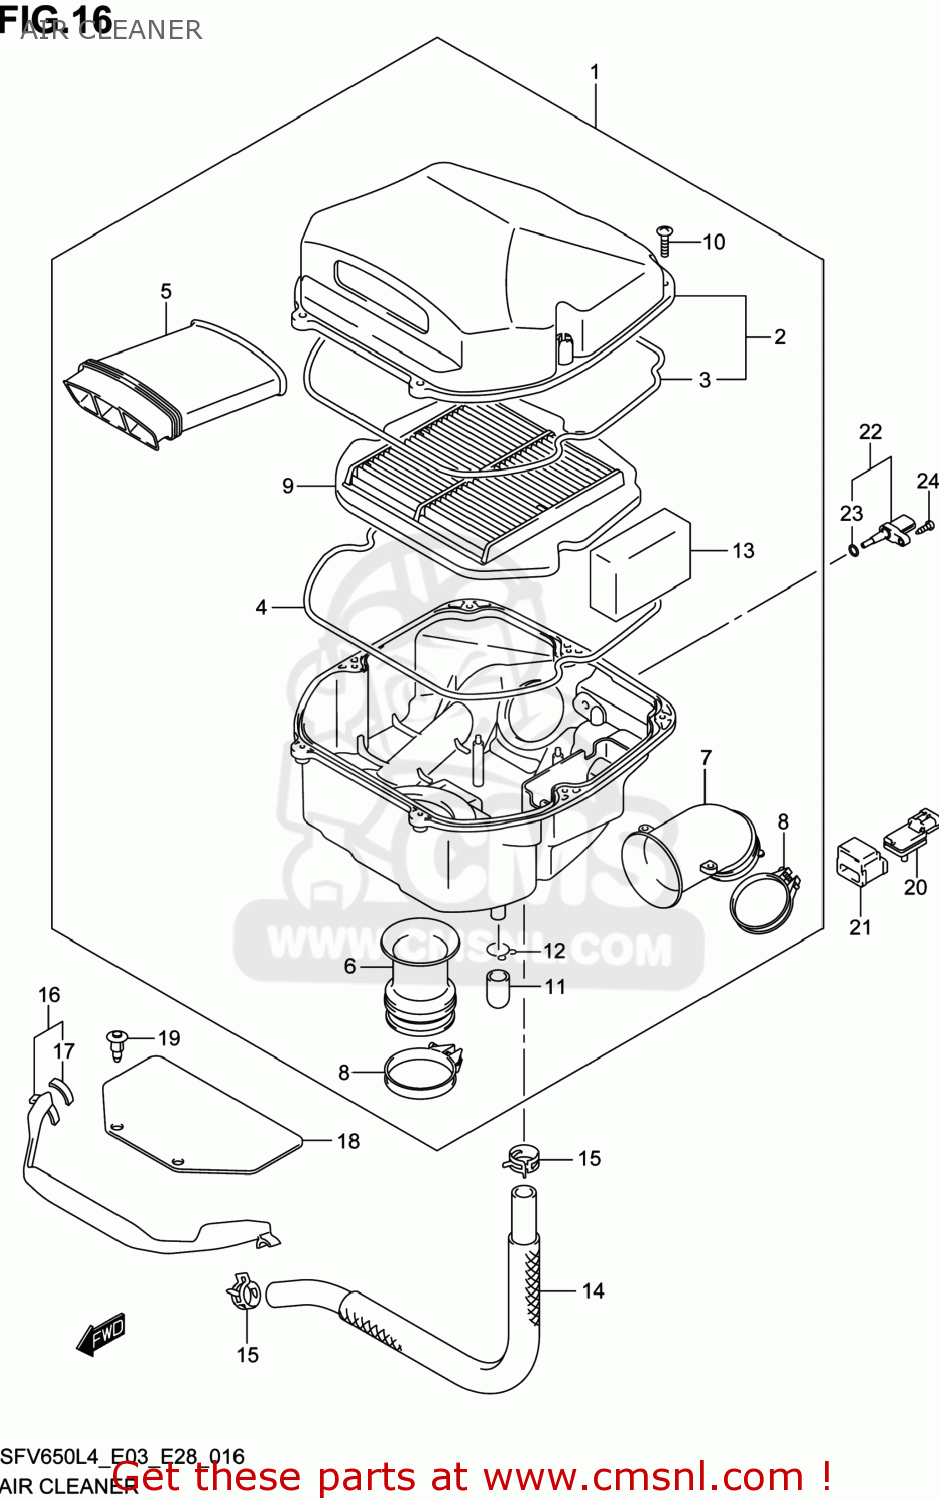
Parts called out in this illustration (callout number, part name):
1	CLEANER ASSY,AIR
2	CAP,AIR CLEANER
3	GASKET (NAS)
4	GASKET (NAS)
5	TUBE,INLET
6	TUBE,OUTLET
7	TUBE,OUTLET
8	CLAMP,OUTLET TUBE
9	FILTER,AIR CLEANER
10	SCREW
11	PLUG
12	CLIP
13	FILTER,BREATHER
14	TUBE,BREATHER
15	CLIP
16	COVER,CLEANER INLET
17	CUSHION
18	SHEET,CLEANER INLET
19	CLIP(BLACK)
20	SENSOR,PRESSURE
21	HOLDER,SENSOR
22	SENSOR,AIR TEMP
23	O RING
24	SCREW
